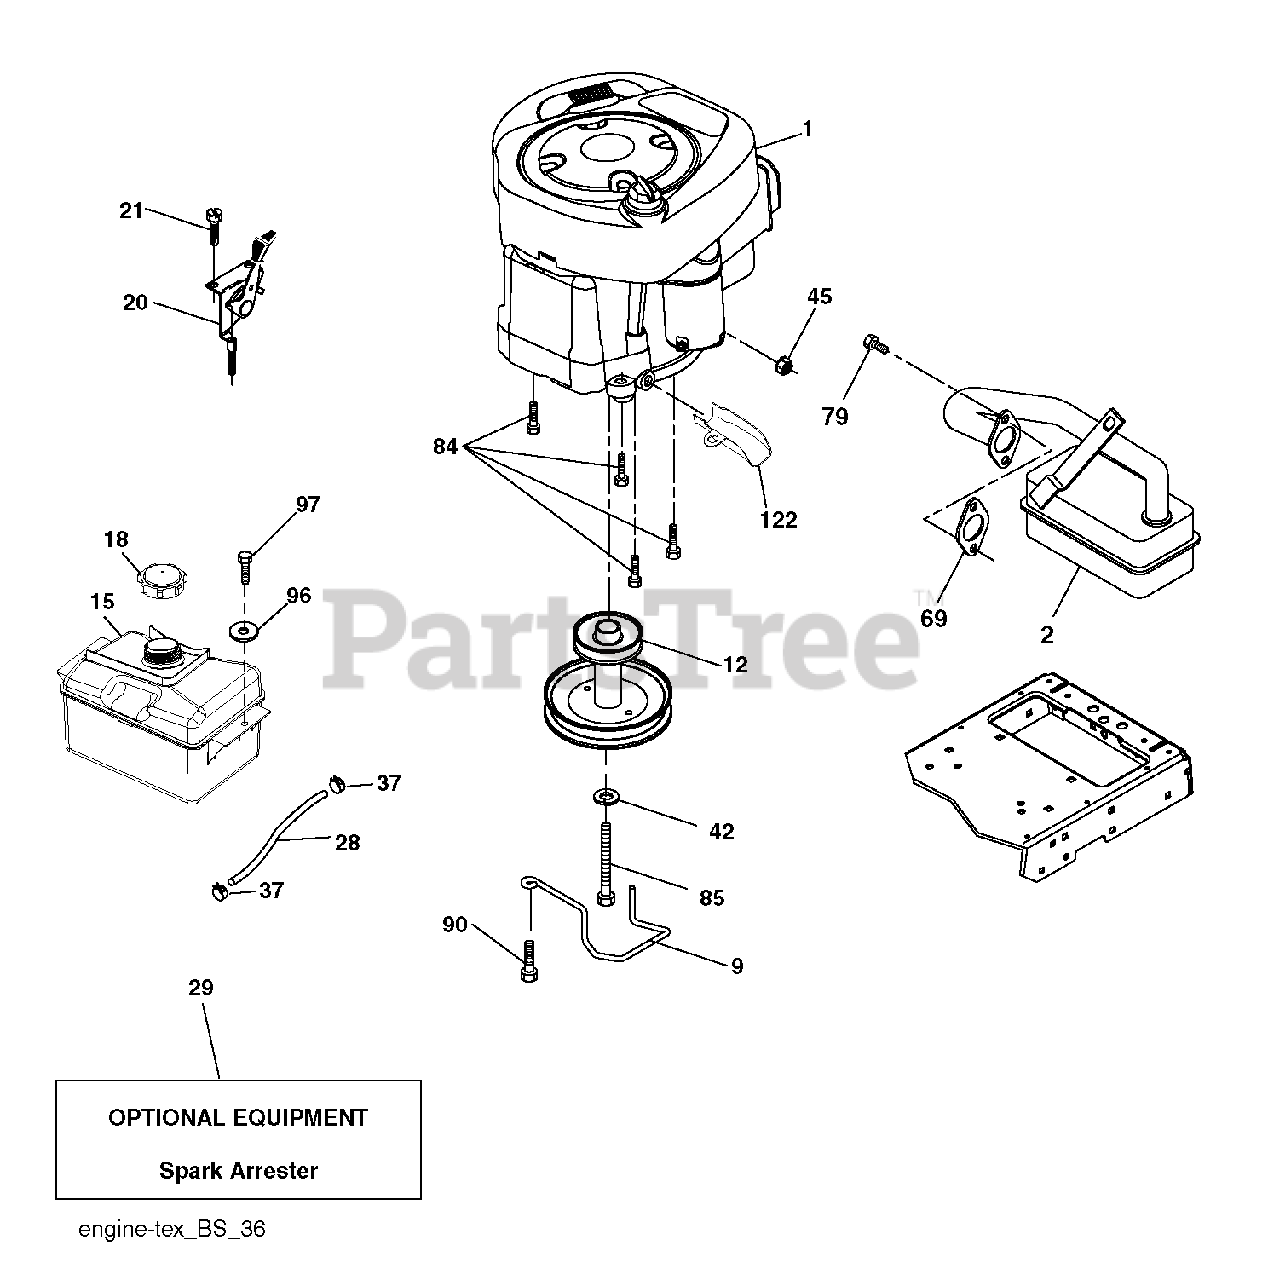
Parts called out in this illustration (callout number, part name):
2	MUFFLER.B&S.MODEL.21.11HP.OHV
9	KEEPER.BELT.ENGINE.3.25
12	PULLEY ENGINE
15	RP TANK FUEL FRT 1.5 GAL
18	CAP ASM.FUEL.2.25"FR.
21	SCREW.#10 X 0.750.BOS (2 2)
28	LINE.FUEL.20"FRONT.EMI
29	KIT.SPARK ARRESTOR(392390 B&S)
37	HOSE CLAMP
42	LOCKWASHER
45	NUT
79	SCREW.SOCKET HD.5/16-1
84	SCREW.3/8-16
85	BOLT HEX 7/16-20X4-1/4"
90	SCREW 3/8-16X1
96	WASHER
97	SCREW HEXWSHR 1/4-20X3/4
122	EXTENSION DRAIN OIL
